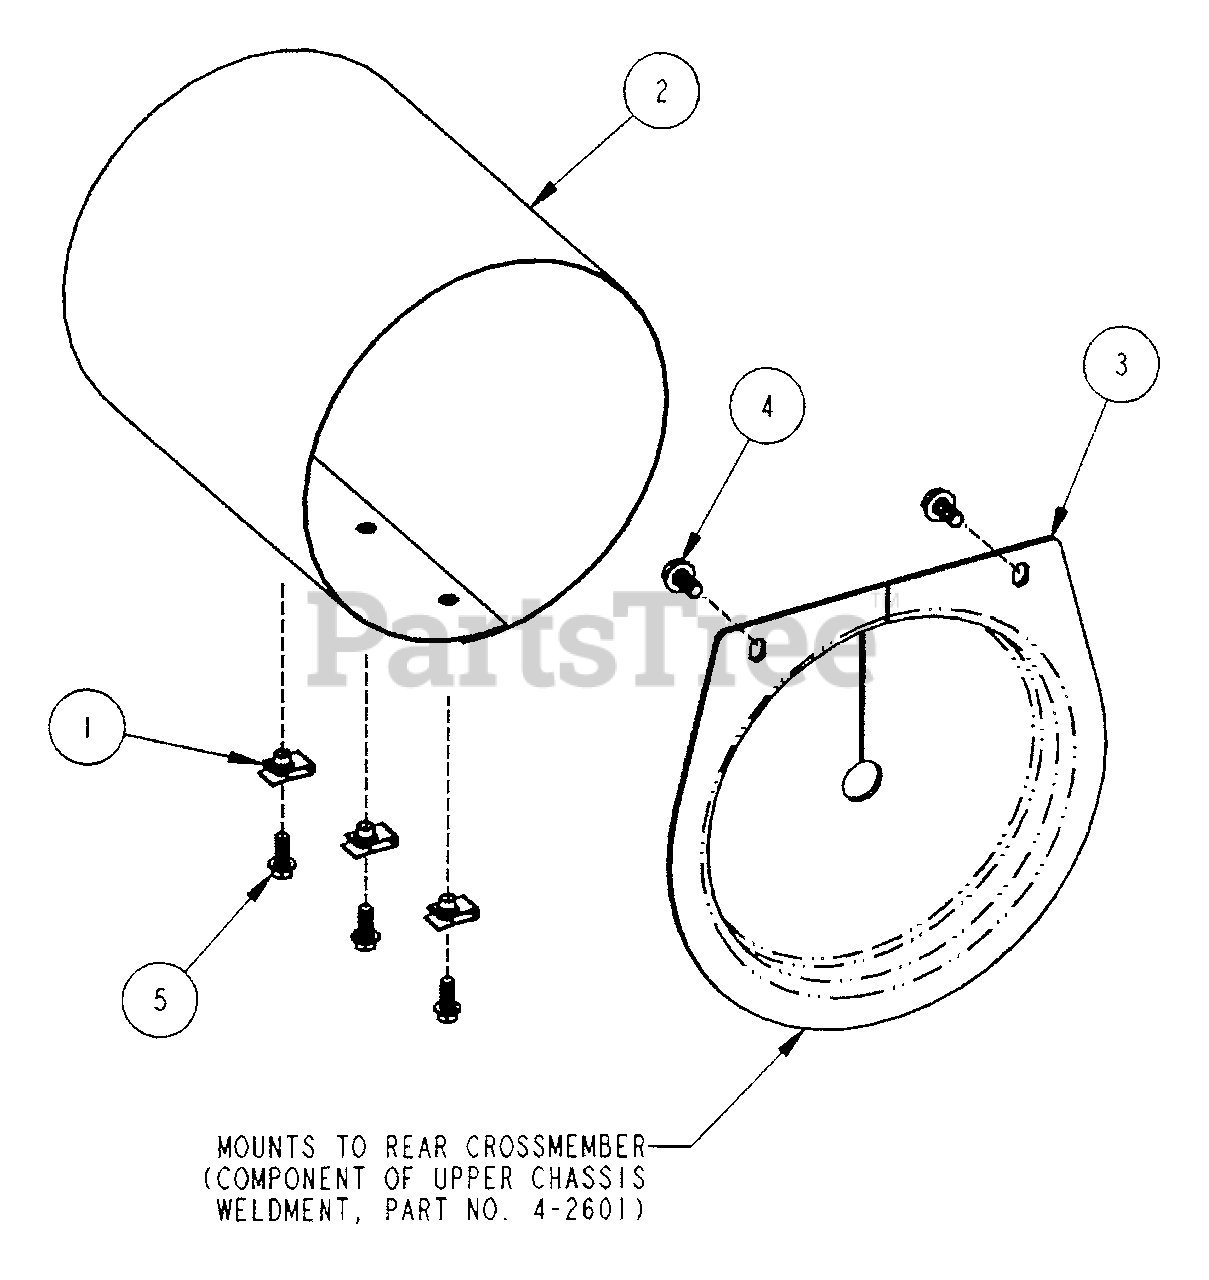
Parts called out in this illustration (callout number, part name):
1	U-NUT, 1/4-20
2	SCREEN, Air Intake
3	MOUNT, Air Intake
4	SCREW, 5/16-18 x 5/8" Self-Tapping
5	SCREW, 1/4-20 Hex Flange Lock
